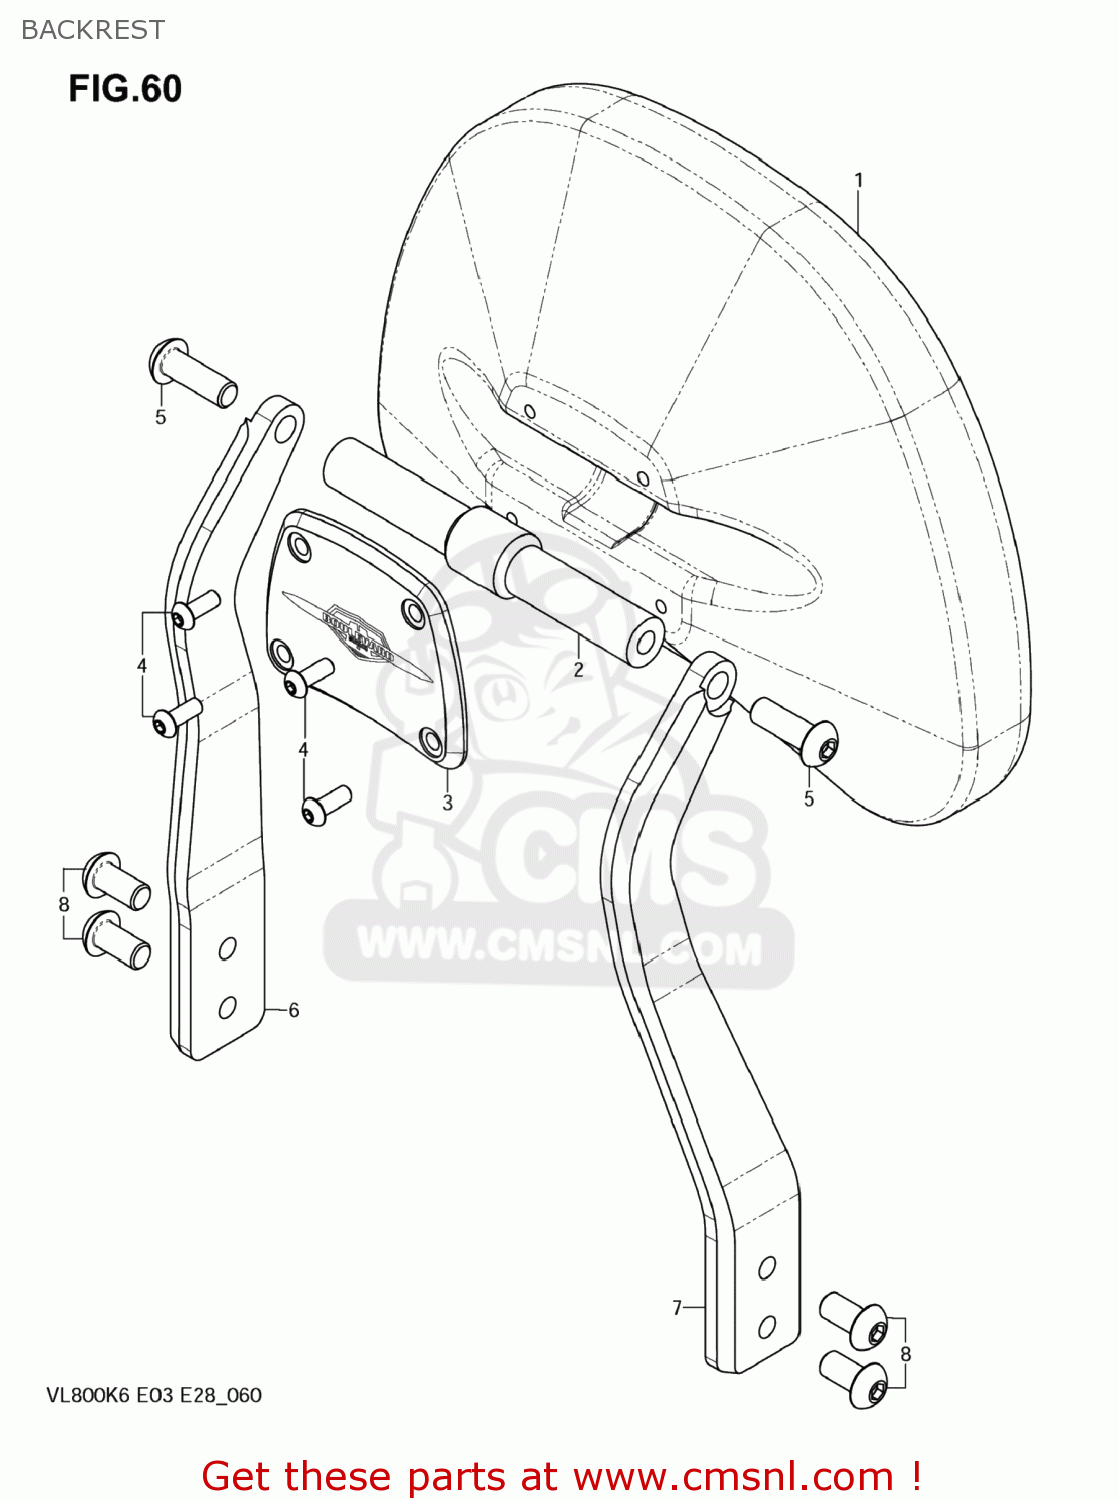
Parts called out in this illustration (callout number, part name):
1	PAD ASSY
1A	.PAD COVER
2	CROSSBAR
3	BACK PLATE
4	SCREW, M6X1.0X20
5	SCREW, M10X1.5X25
6	UPRIGHT, LH
7	UPRIGHT, RH
8	SCREW, M10X1.5X20
9	BACKREST MOUNT PLATE, LH
10	BACKREST MOUNT PLATE, RH
10A	C50T BKRST PLT
11	SPACER, 19ODX8.5IDX6.5T
11A	C50T 2X6.5MM SP
11B	C50T BKRST BOLT
12	SADDLEBAG SUPPORT, LH
13	SADDLEBAG SUPPORT, RH
13A	C50T SDLBAG SPT
13B	C50T 2X19MM SPA
14	SADDLEBAG ASSY, LH
14A	C50T SDLBAG K9&
15	SADDLEBAG ASSY, RH
15A	C50T SDLBAG K9&
16	BOLT, M8X1.25X85
17	TOPHAT WASHER, SADDLEBAG
18	C50T SADDLEBAG
20	BLVD SADDLBAG E
